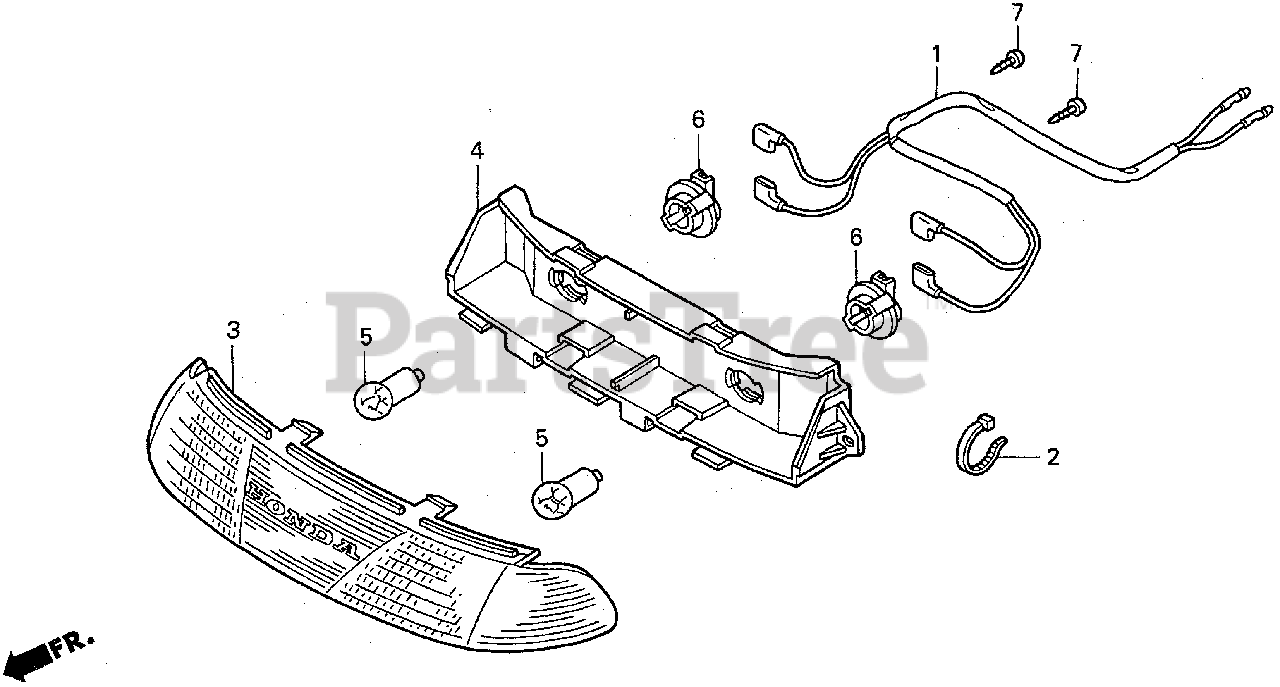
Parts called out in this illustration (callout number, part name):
1	SUB-WIRE HARNESS, HEADLIGHT
2	TIE, CABLE
3	LENS, HEADLIGHT
4	REFLECTOR, HEADLIGHT
5	BULB (12VX25W)
6	SOCKET ASSY., HEADLIGHT
7	SCREW, TAPPING (5X16)
